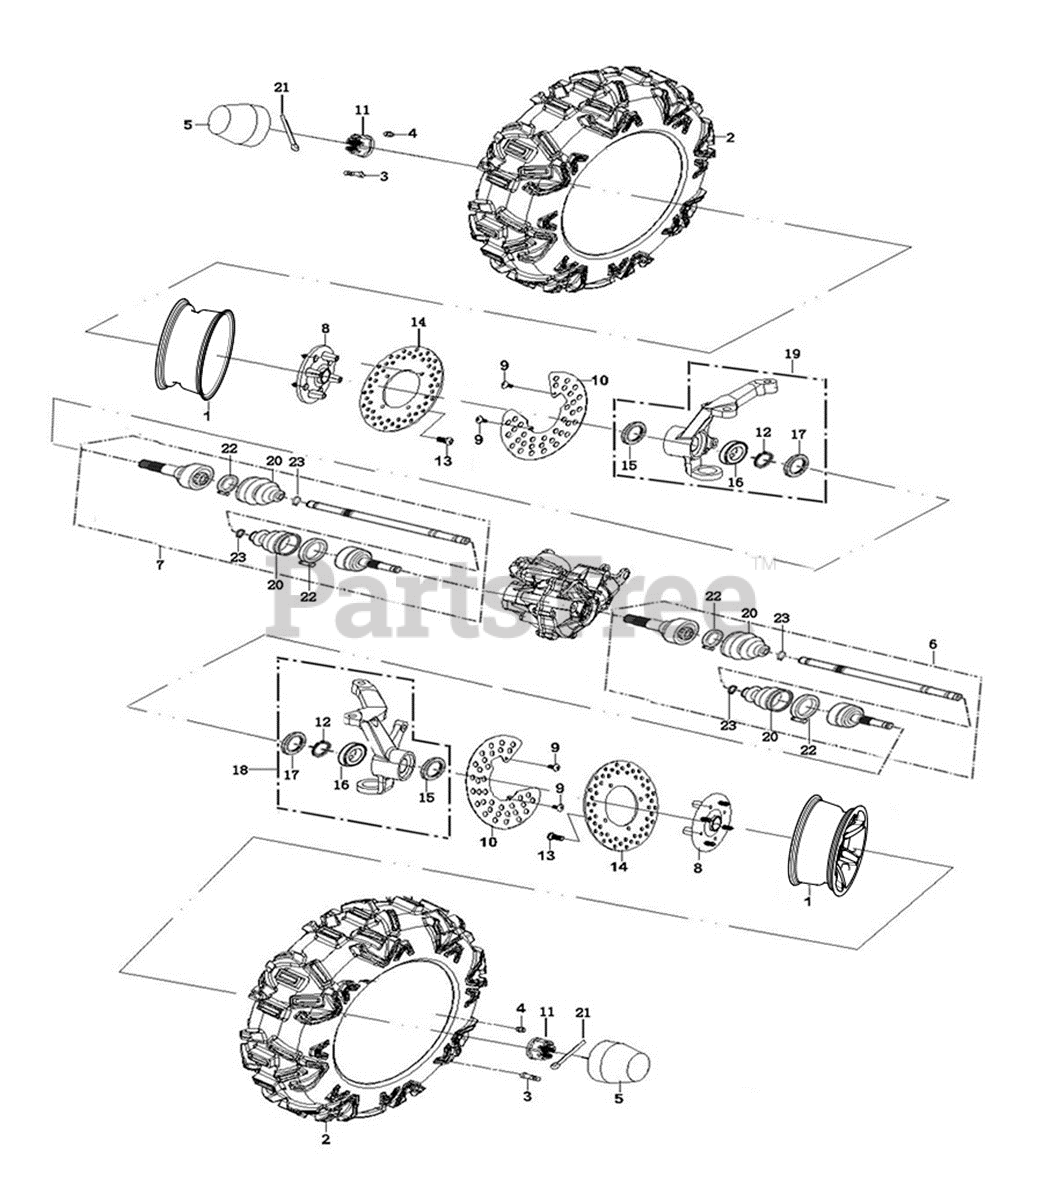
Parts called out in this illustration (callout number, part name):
1	RIM - FRONT
1	FRONT RIM - BLACK
2	TIRE RADIAL - FRONT
3	VALVE-CYCLE
4	TAPER NUT M10X1.25
5	DUST COVER HUB
6	FRONT LEFT CONSTANT VELOCITY JOINT
7	FRONT RIGHT CONSTANT VELOCITY JOINT
8	FRONT WHEEL HUB
9	SCREW M6X12
10	FRONT DISC BRAKE SHIELD
11	SLOTTED NUT M24X1.5
13	BOLT M8X15-15X5
14	DISC BRAKE - FRONT
15	OUTER OIL SEAL
17	INNER OIL SEAL
18	STEERING KNUCKLE FRONT LEFT ASM
19	STEERING KNUCKLE FRONT RIGHT ASM
20	AXLE RUBBER BOOT
21	COTTER PIN 3.2X50
22	CLAMP - LARGE
23	CLAMP - LARGE
